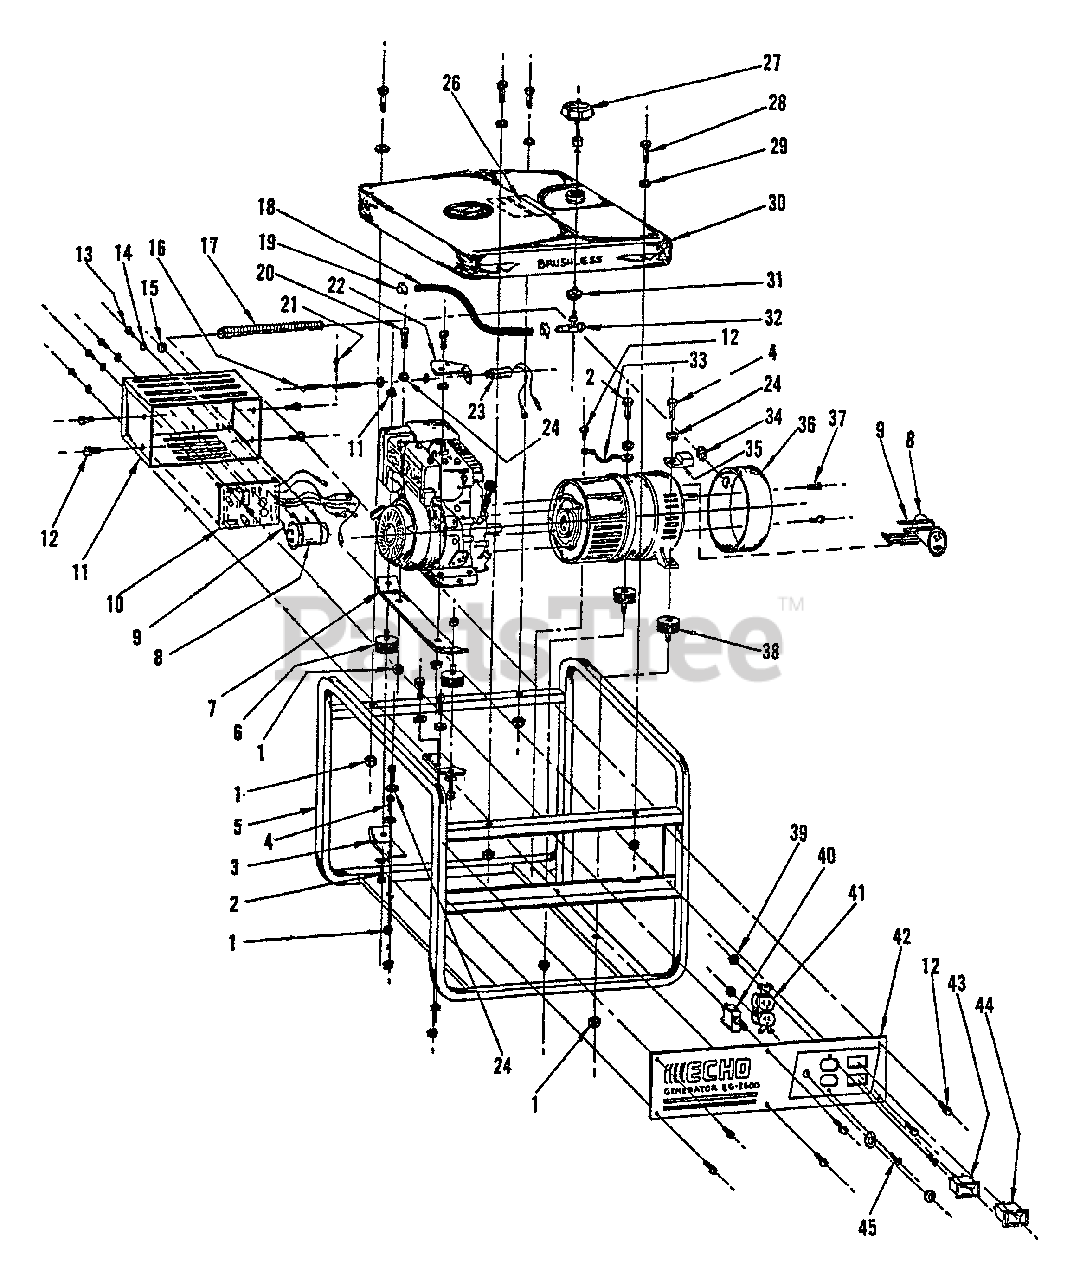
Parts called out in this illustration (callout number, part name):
1	LOCKNUT - 5/16-18
2	5/16-18X5/8 HHS
3	BRACKET, FOCUS
4	5/16-18X7/8 HHS
5	FRAME
6	ISOLATOR, VIBRATION
7	RAIL, FOCUS
8	CAPACITOR - 50UF 370V
9	TIE, CABLE
10	CIRCUIT, ECHO-MIZER
11	BOX, CONTROL
12	SCREW - 10-24
13	6-32X 1/4 RHS
14	LOCKWASHER - 6
15	GROMMET
16	SPRING, ECHO-MIZER
17	CONDUIT - 12"
18	LINE, FUEL - 24"
19	CLAMP - 1/4"
20	BOLT - 5/16-18 X 1-1/2"
21	PIN, SPLIT
22	PIN, SPLIT
23	SOLENOID ASSY
24	LOCKWASHER - 5/16"
26	LABEL - SAFETY
27	CAP, FUEL
28	HHS 5/16-18X1.75
29	LOCKWASHER - 5/16"
30	TANK, FUEL - 3.5 GALLON
31	GROMMET
32	VALVE, FUEL TANK
33	LEAD - GROUND
34	GROMMET
35	LUG, GROUND - 1/0-14 CU/AL
36	COVER, END
37	SCREW - 10-24
38	ISOLATOR, VIBRATION
39	NUT - 8-32 -- KEPS
40	BREAKER, CIRCUIT - 15A/250V
41	DUPLEX, 15A/125V
42	PANEL, SILKSCREENED
43	SWITCH, ECHO-MISER
44	SWITCH, IGNITION
45	8-32X3/8 RHS
